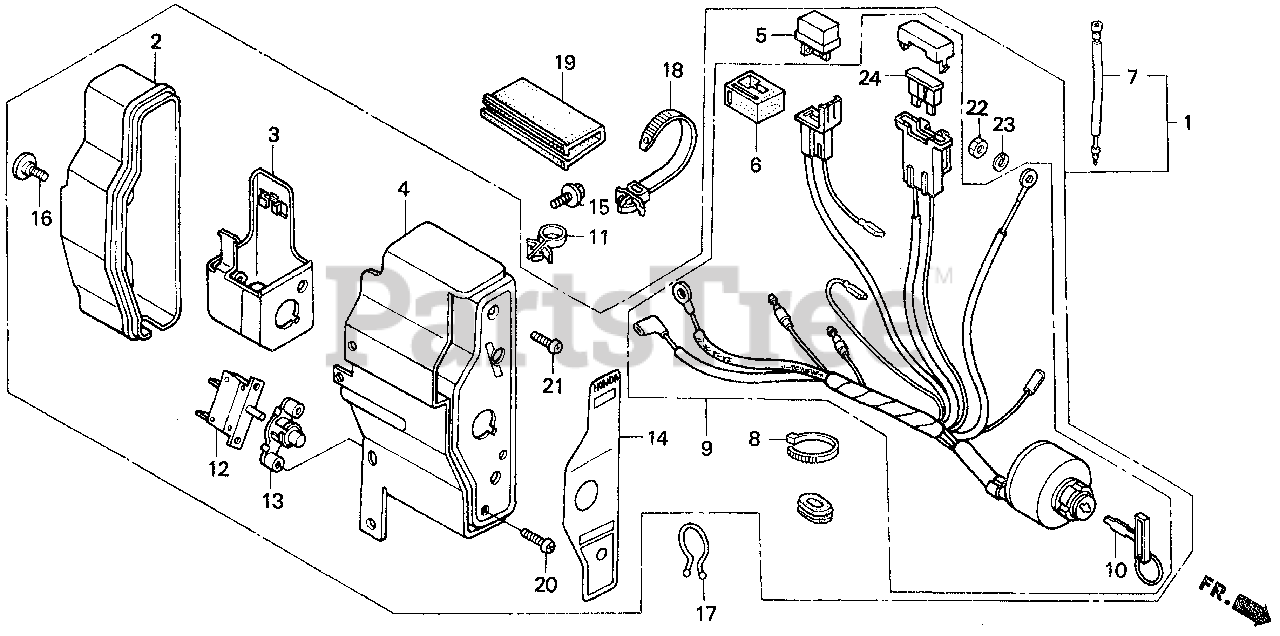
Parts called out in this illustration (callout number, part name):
1	BOX ASSY., CONTROL *NH105* (EXP-ALERT) (MAT BLACK)
1	BOX ASSY., CONTROL *NH105* (EXTERNAL-ALERT) (MAT BLACK)
2	CASE, CONTROL
3	BRACKET, CASE MOUNTING
4	PANEL, CONTROL *NH105* (MAT BLACK)
5	RECTIFIER ASSY., SILICON (STANLEY)
6	SUSPENSION, CONNECTOR
7	SUB-HARNESS
8	BAND
9	SWITCH ASSY., COMBINATION
10	KEY
11	HOLDER, STOP SWITCH WIRE
12	PROTECTOR, CIRCUIT (1.0A)
13	LENS ASSY., PROTECTOR
14	PANEL, CONTROL BOX (EXTERNAL)
15	BOLT, FLANGE (6X12) (CT200)
16	SCREW, SPECIAL (6X12)
17	CLIP, PURSE LOCK
18	STRAP, CABLE (118MM) *NH1L* (BLACK)
19	TUBE, FASTENER (30)
20	SCREW, PAN (3X12)
21	SCREW, PAN (4X12)
22	NUT, HEX. (4MM)
23	WASHER, SPRING (4MM)
24	FUSE, BLADE (5A)
25	ALERT UNIT, OIL
26	WASHER, PLAIN (4MM)
